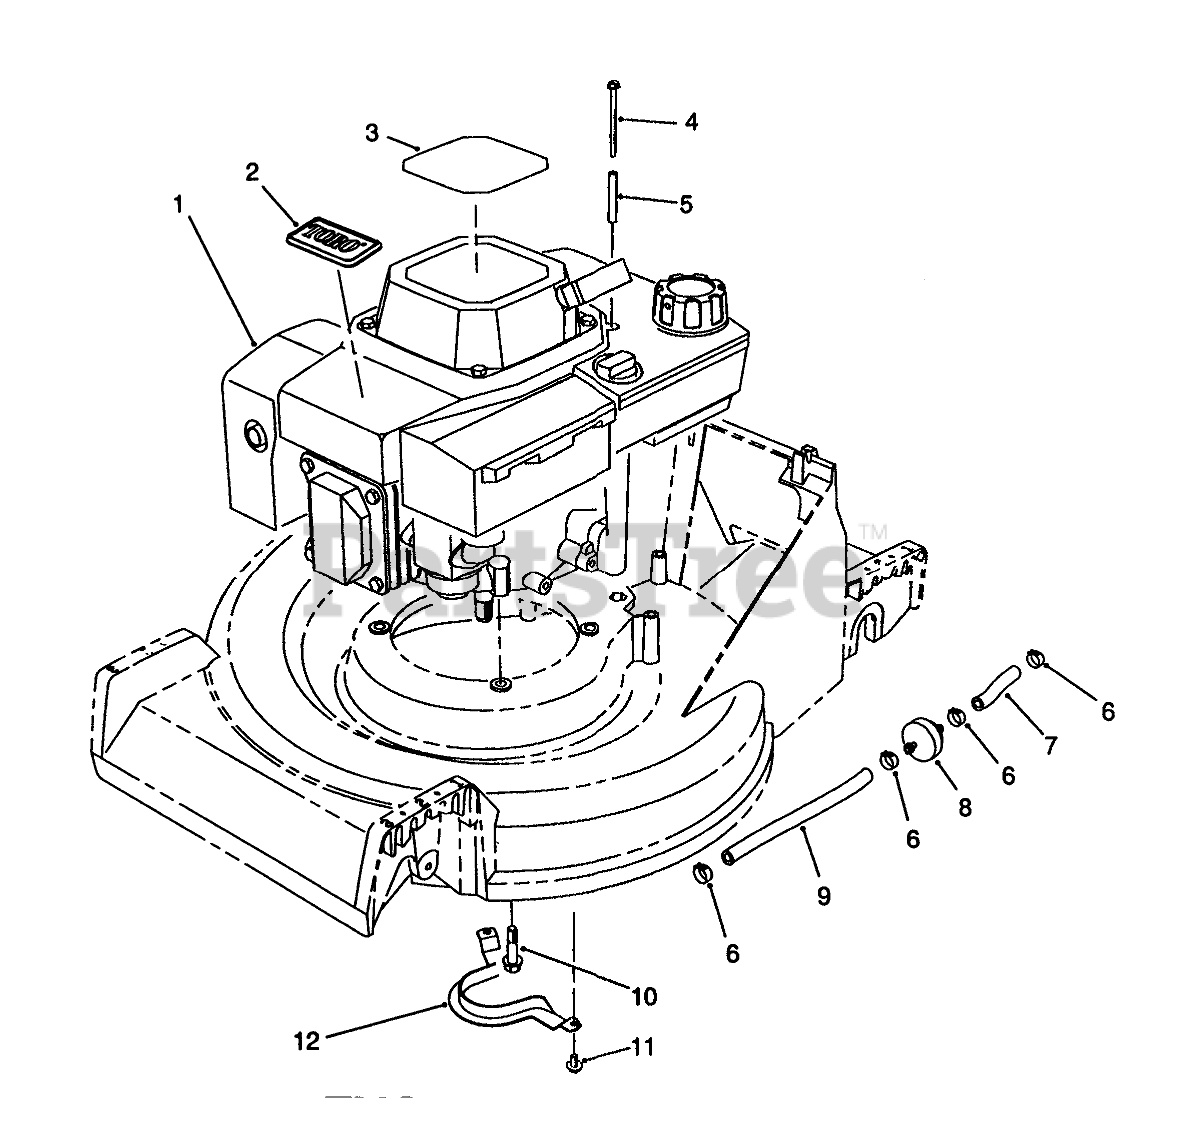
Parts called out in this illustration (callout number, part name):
1	ENGINE ASSY BBC OHV SU
2	TORO LOGO PLT
3	DECAL - OHV RECOIL
4	THRD FORMING SCREW
5	TUBULAR SPACER
6	CLAMP-FUEL LINE
7	Line-Fuel
8	FILTER-FUEL
9	HOSE-FUEL
10	SCREW-HWHTF
11	SCREW-HWHTF
12	Guide-Belt
